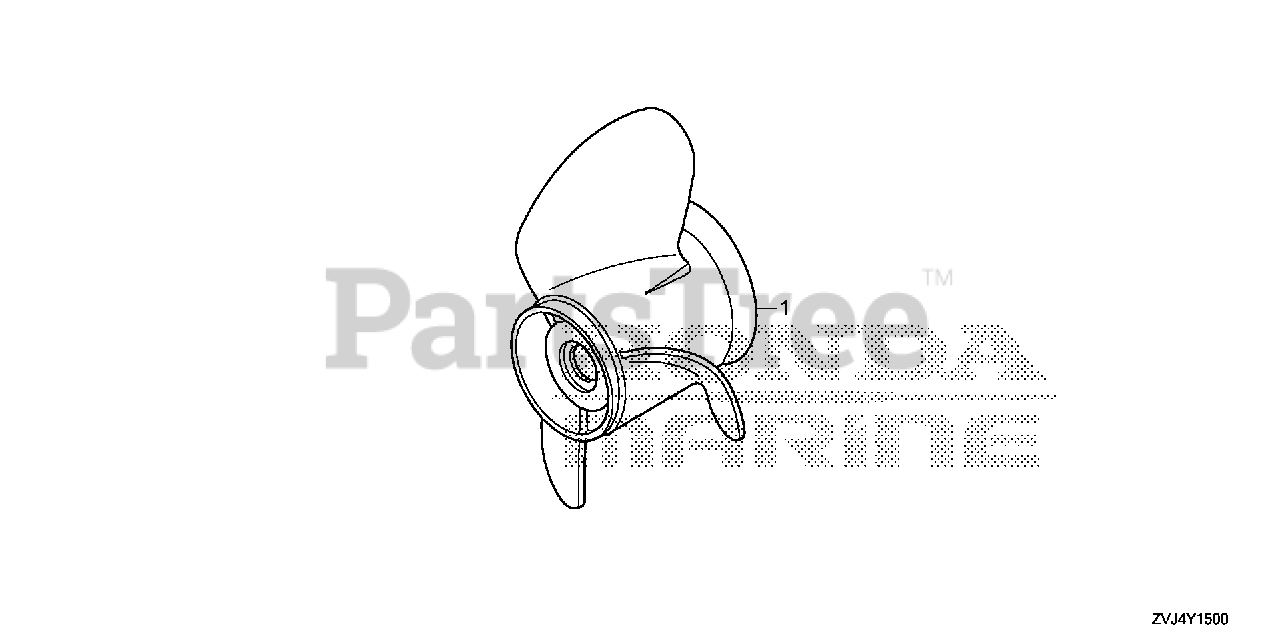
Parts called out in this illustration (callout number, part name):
1	PROPELLER, THREE-BLADE (15-3/4X15)
1	PROPELLER, THREE-BLADE (15-1/2X17)
1	PROPELLER, THREE-BLADE (15-1/4X19)
1	PROPELLER, THREE-BLADE (15X21)
1	PROPELLER, THREE-BLADE (14-3/4X23)
1	PROPELLER, THREE-BLADE (14-1/2X25)
1	PROPELLER, THREE-BLADE (14-1/2X27)
